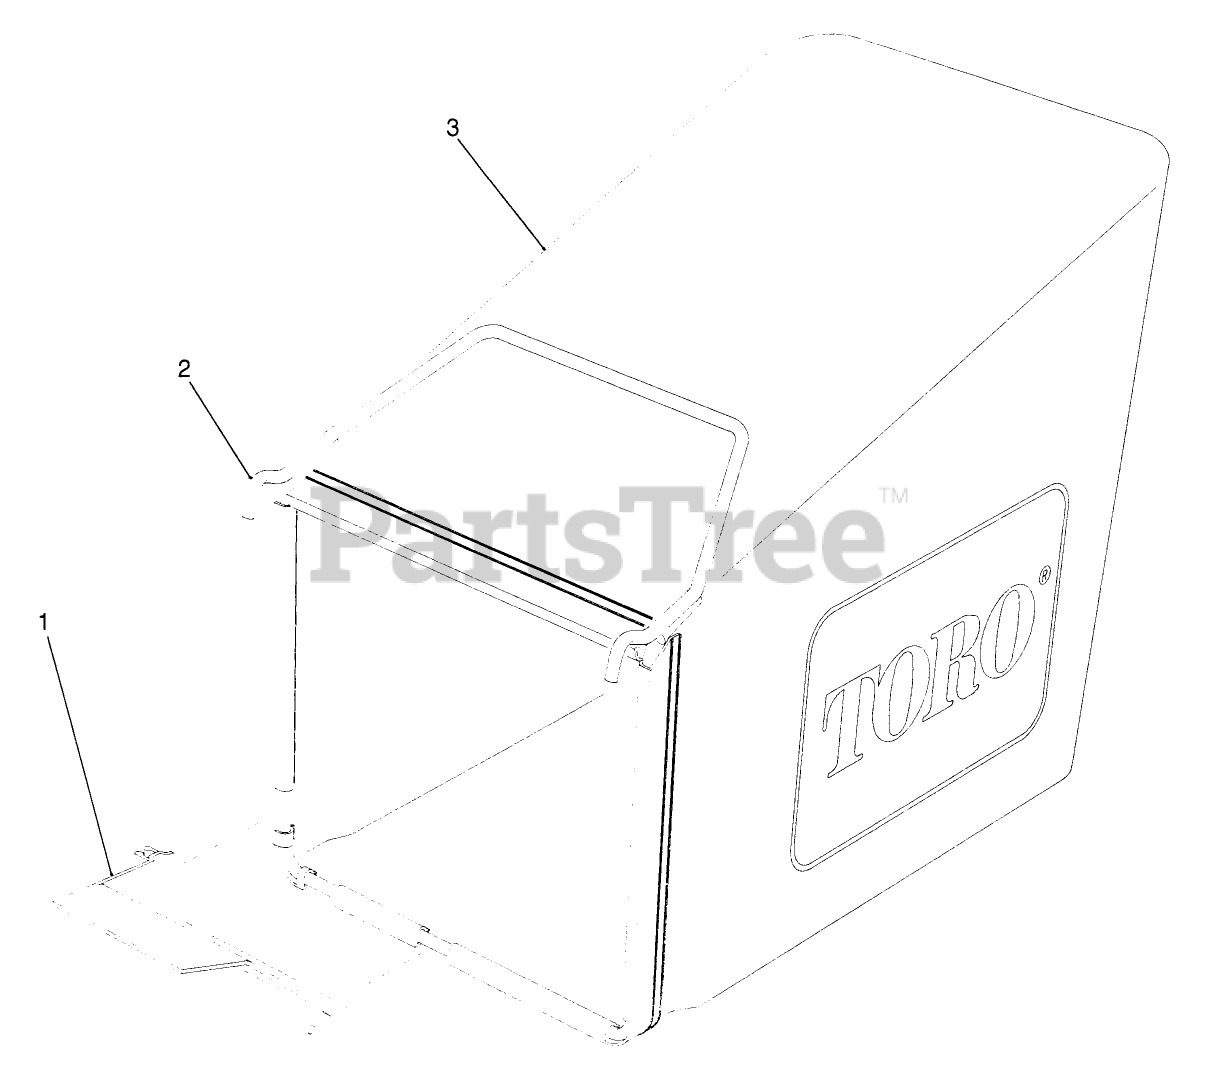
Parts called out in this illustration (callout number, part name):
1	BAG RAMP
2	Frame
3	GRASS BAG ASSEMBLY
